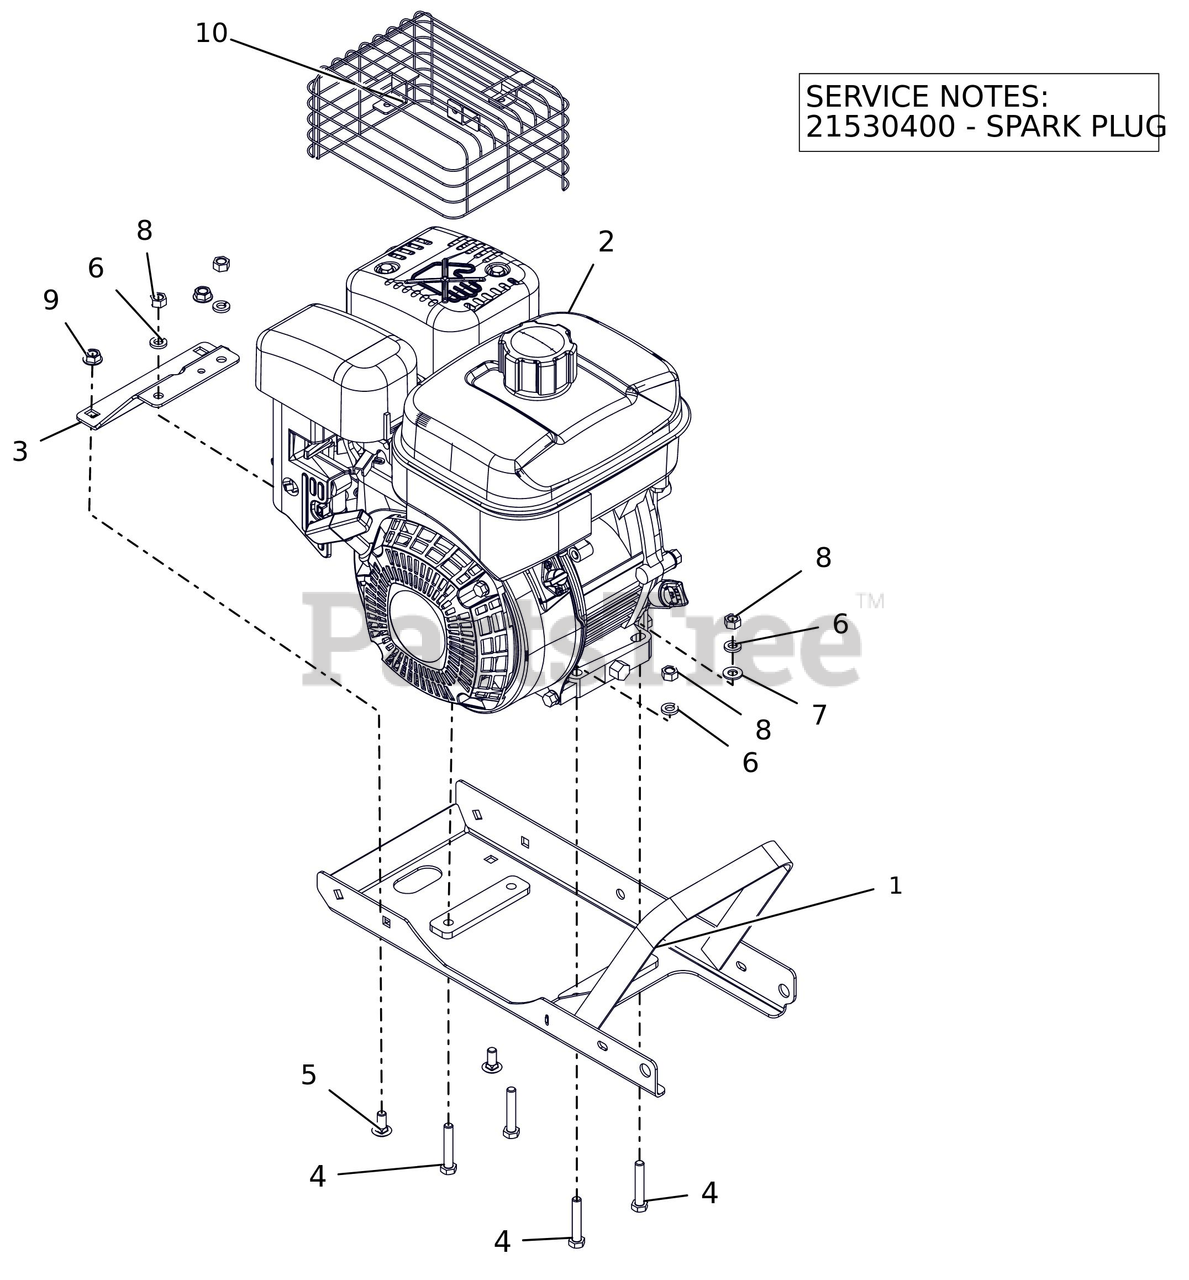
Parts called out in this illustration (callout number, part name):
1	FRAME,EDGER
2	ENGINE,SUBARU 6HP SP170 (CARB)
2	PLUG, SPARK - TEC. SNO-THRO
3	BRACKET, REINFORCEMENT
4	@BLT-HEX .31-18X1.75 GR5 YWZC
5	@BLT-RDHDSQNK .31-18X.75 G5YZ
6	WSHR-LK .312X.097 HVY YWZC
7	@WSHR-FL-STL.344X.688X.065YWZC
8	@NUT-HEX .31-18 YWZC
9	@NUT-LK-TOP-FLG .31-18 YWZC
10	GUARD,MUFFLER,SUB 20A-37303-11
